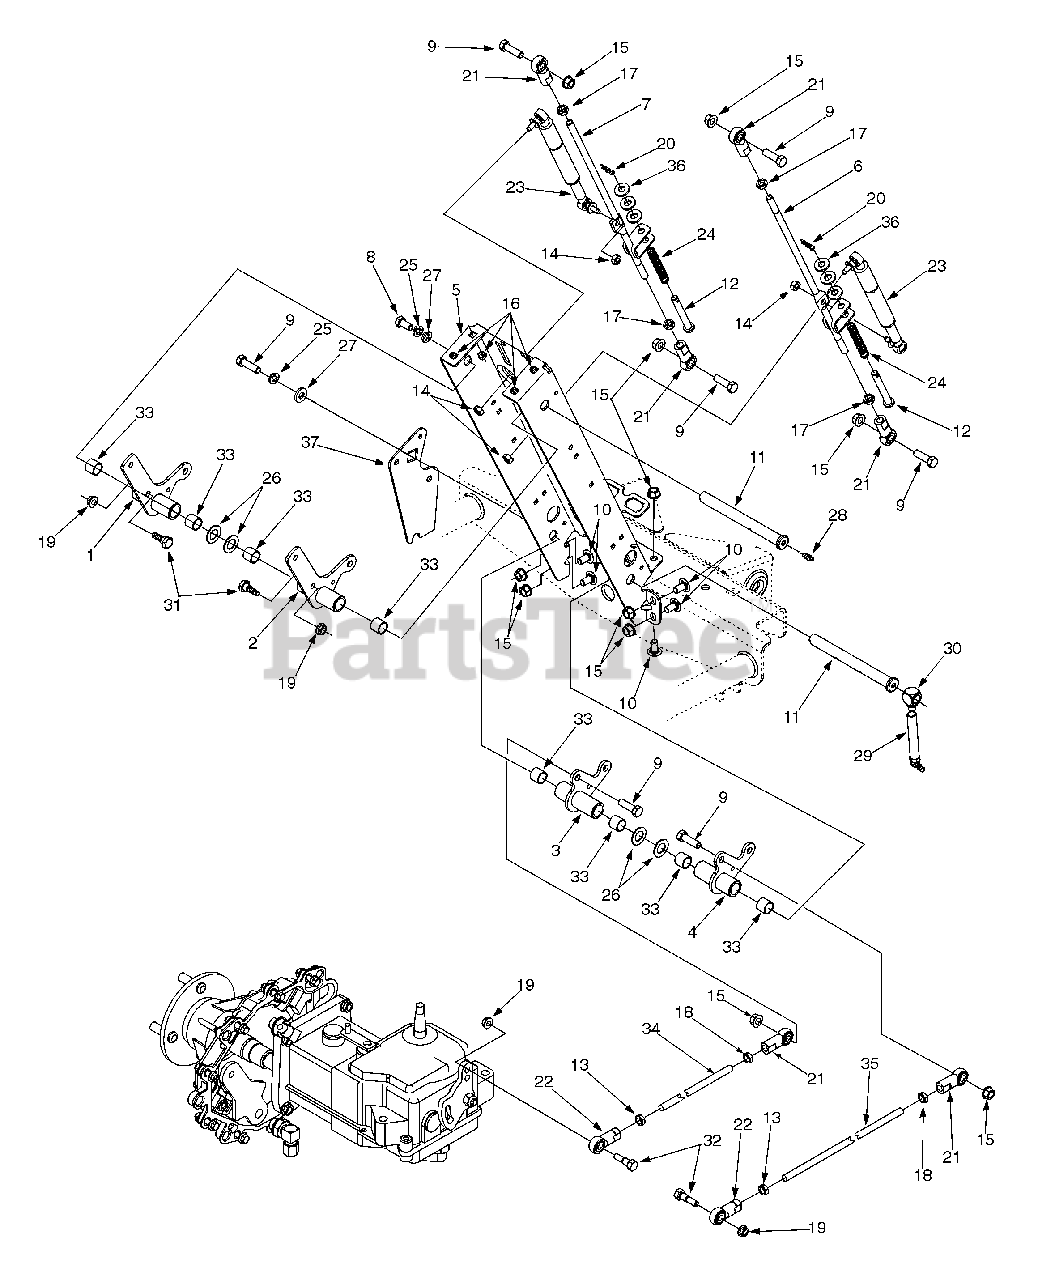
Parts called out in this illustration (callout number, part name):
1	Bellcrank Ass'y Upper LH
4	Bellcrank Ass'y Lower RH
7	Rod Ass'y Control LH
8	Hex Cap Screw 3/8-16 x .75
9	Hex Cap Screw 3/8-16 x 1.25
10	Carriage Bolt 3/8-16 x .75
11	Control Shaft
12	Pin
13	Hex Jam Nut LH 3/8-24
14	Hex Center Lock Nut
15	Hex Flange Lock Nut 3/8-16
16	Retainer 1/4-20
17	Hex Jam Nut 3/8-24
18	Hex Jam Nut 3/8-24
19	Hex Flange Lock Nut 5/16-18
20	Cotter Pin
21	Spherical Rod End RH 3/8-24
22	Spherical Rod End LH 3/8-24
23	Damper Cylinder
24	Spring Compression
25	Lock Washer 3/6
26	Thrust Washer .625 ID x 1.12 OD
27	Flat Washer.406 ID x.875 OD
28	Grease Fitting
29	Grease Fitting w/Tube
30	Adapter 1/4-20
31	Shoulder Bolt .437 Dia. x .268
32	Shoulder Bolt
33	Sleeve Bearing
34	Control Rod LH 31-5/8
35	Control Rod RH 35-3/8
36	Flat Washer .406 ID x .87 OD
37	Plate Support
